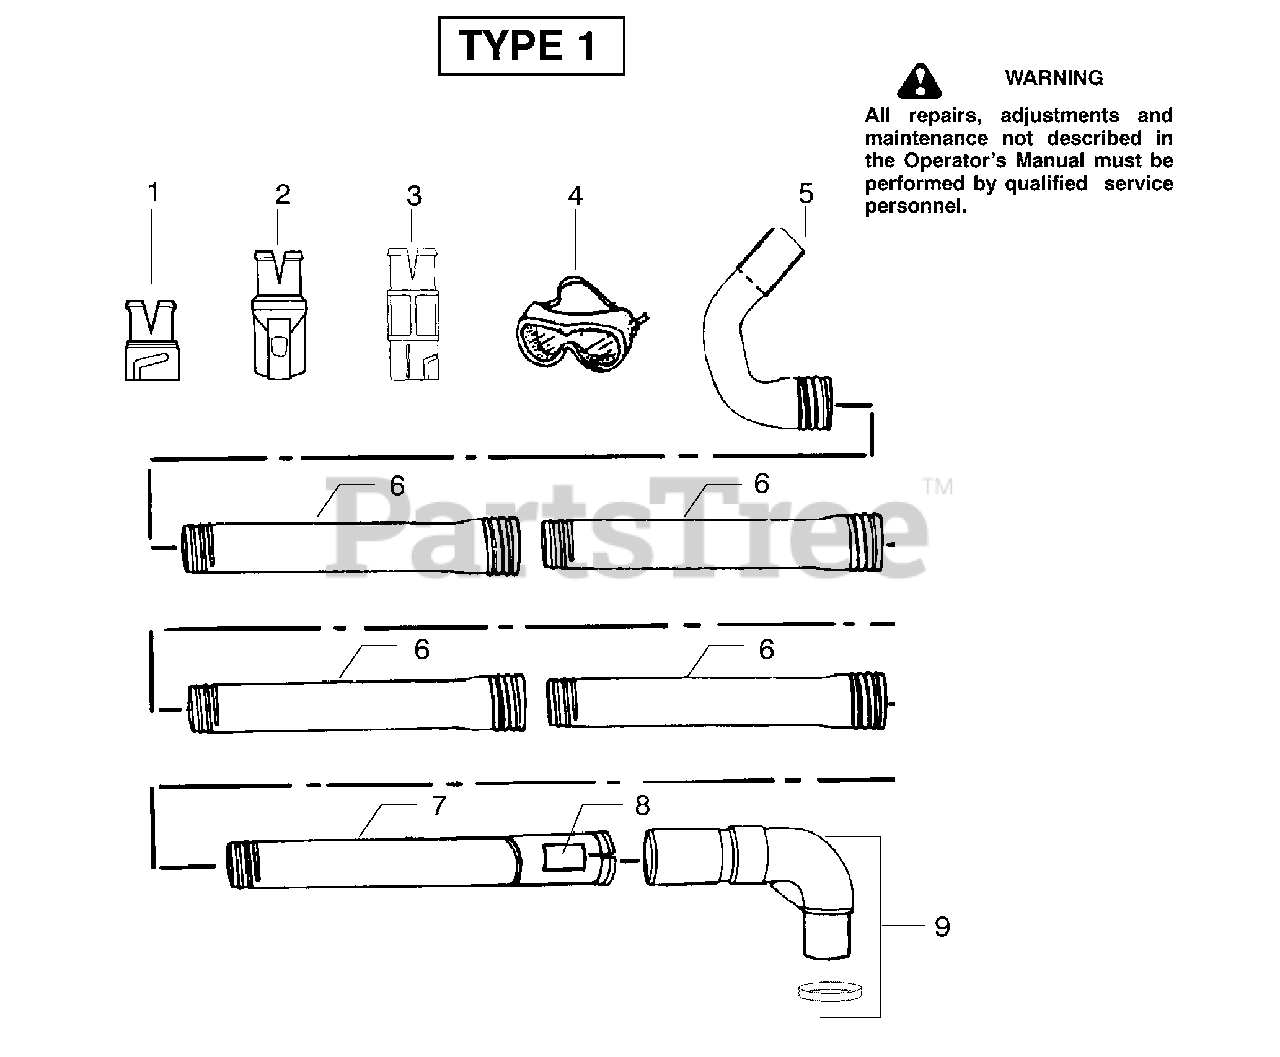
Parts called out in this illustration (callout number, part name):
1	Adapter-Tube
2	Adapter-Gutter Kit
4	Goggles
6	Tube-Extension
7	Pivot Tube
8	Decal-Warning
9	Elbow&Spacer Ring
